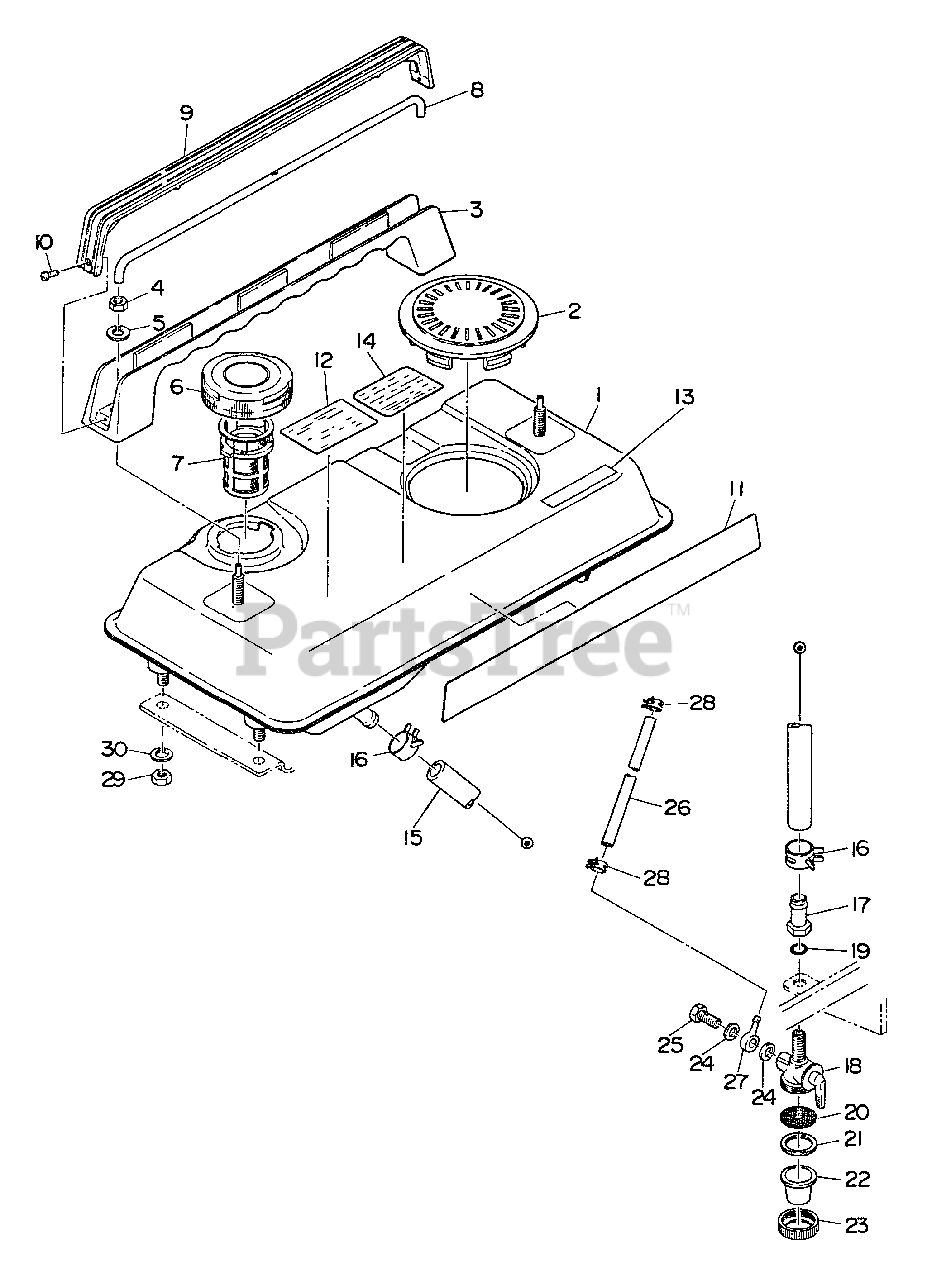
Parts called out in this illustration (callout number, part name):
1	FUEL TANK ASSY
2	COVER
3	HANDLE
4	NUT
5	LOCKWASHER
6	CAP ASSY
7	FILTER, FUEL
8	PIPE - BREATHER
9	COVER, HANDLE
10	SCREW
11	LABEL, MODEL EG-1200
12	LABEL - CAUTION
13	LABEL - SPARK ARRESTER
14	LABEL - DANGER
15	RUBBER PIPE (11.5 X 17.5 X 230mm)
16	CLAMP, HOSE
17	CONNECTOR
18	FILTER, FUEL
19	O-RING
24	WASHER
26	RUBBER PIPE (6 X 12 X 160mm)
27	BOLT, BANJO
28	CLAMP, HOSE
29	NUT
30	LOCKWASHER
